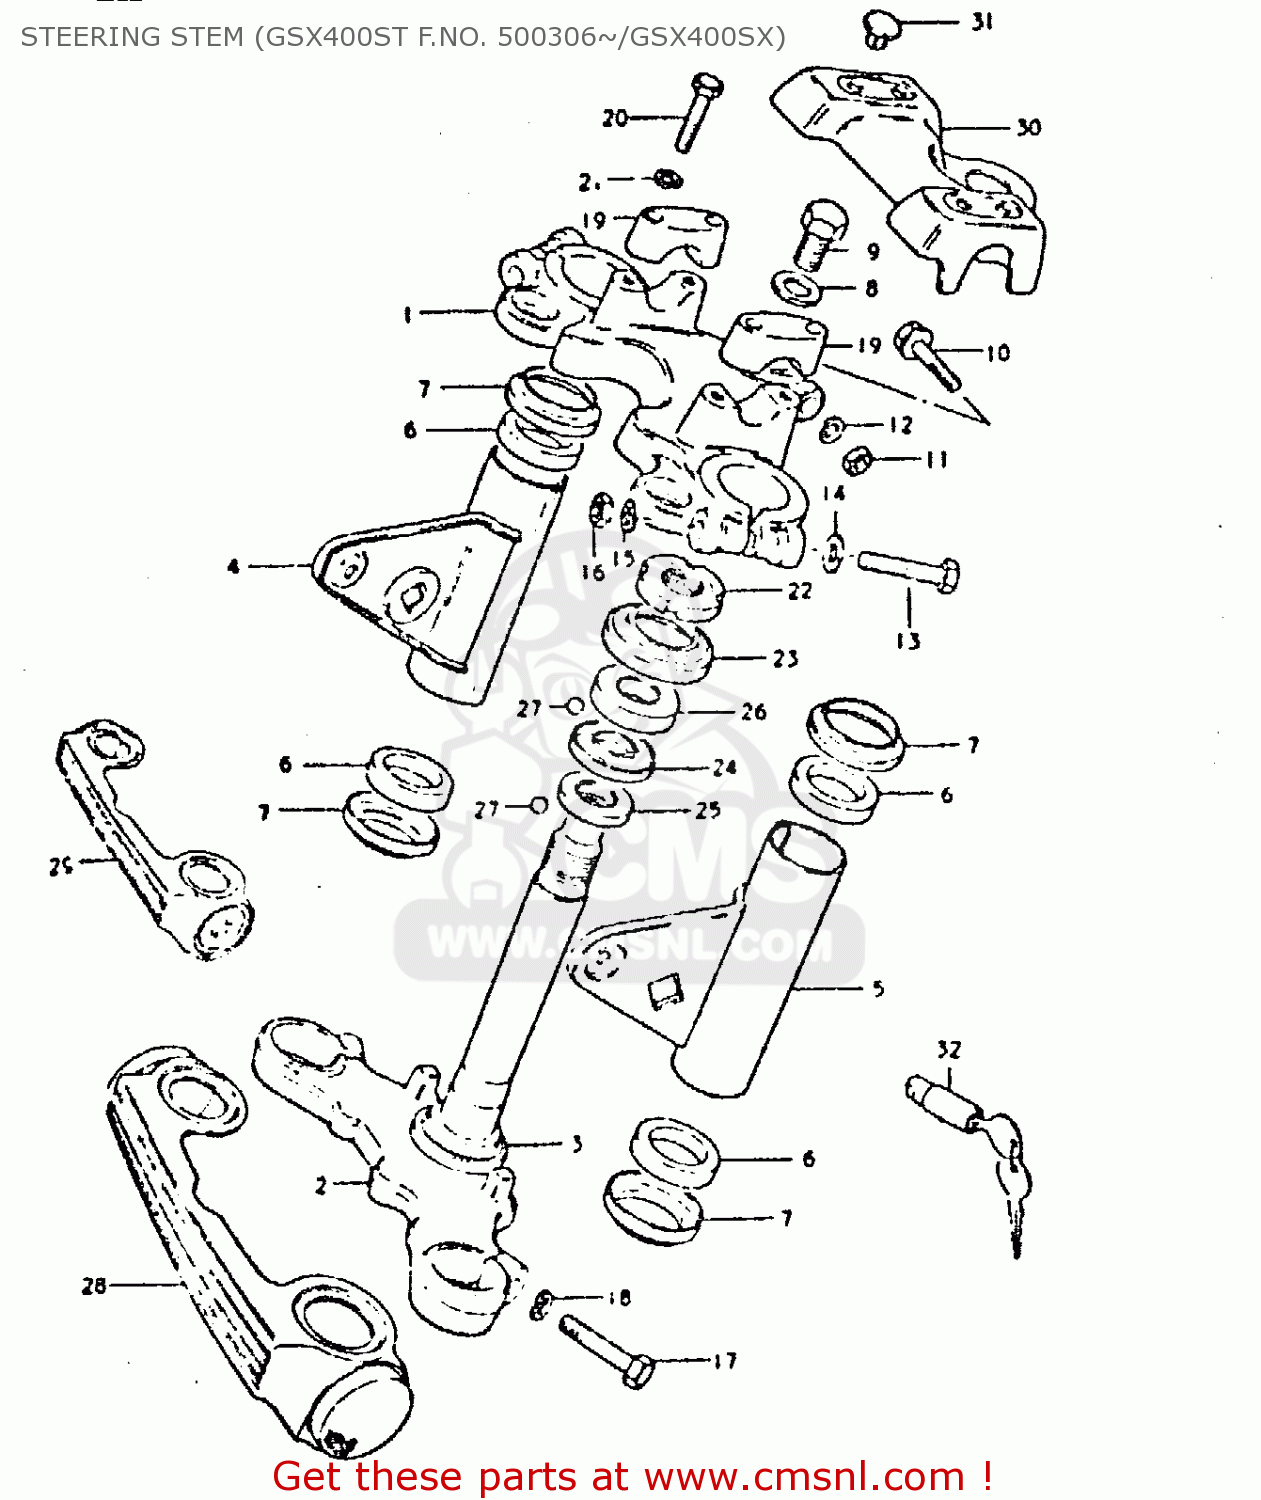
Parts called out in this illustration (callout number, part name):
1	HEAD,STEERING STEM
2	STEERING STEM
3	RACE, OUTER LOWER
4	BRACKET,HEADLAMP,RIGHT
5	BRACKET,HEADLAMP,LEFT
6	CUSHION,HEADLAMP BRACKET
7	CAP,HEADLAMP BRACKET
8	WASHER
9	BOLT(12X20)
10	BOLT
11	NUT
12	LOCK WASHER
13	BOLT 10X55
14	WASHER
15	LOCK WASHER
16	NUT
17	BOLT 10X40
18	LOCK WASHER
19	HOLDER,HANDLE UPR
20	BOLT 8X35
21	WASHER,LOCK,8.
22	NUT,STEERING STEM(25X44X10)
23	DUST SEAL,STEERING,UPPER
24	RACE, INNER UPPER
25	RACE, INNER LOWER
26	RACE, OUTER UPPER
27	BALL
28	COVER,FR FORK
30	PAD,HANDLE
31	CAP(OD:19.5)
